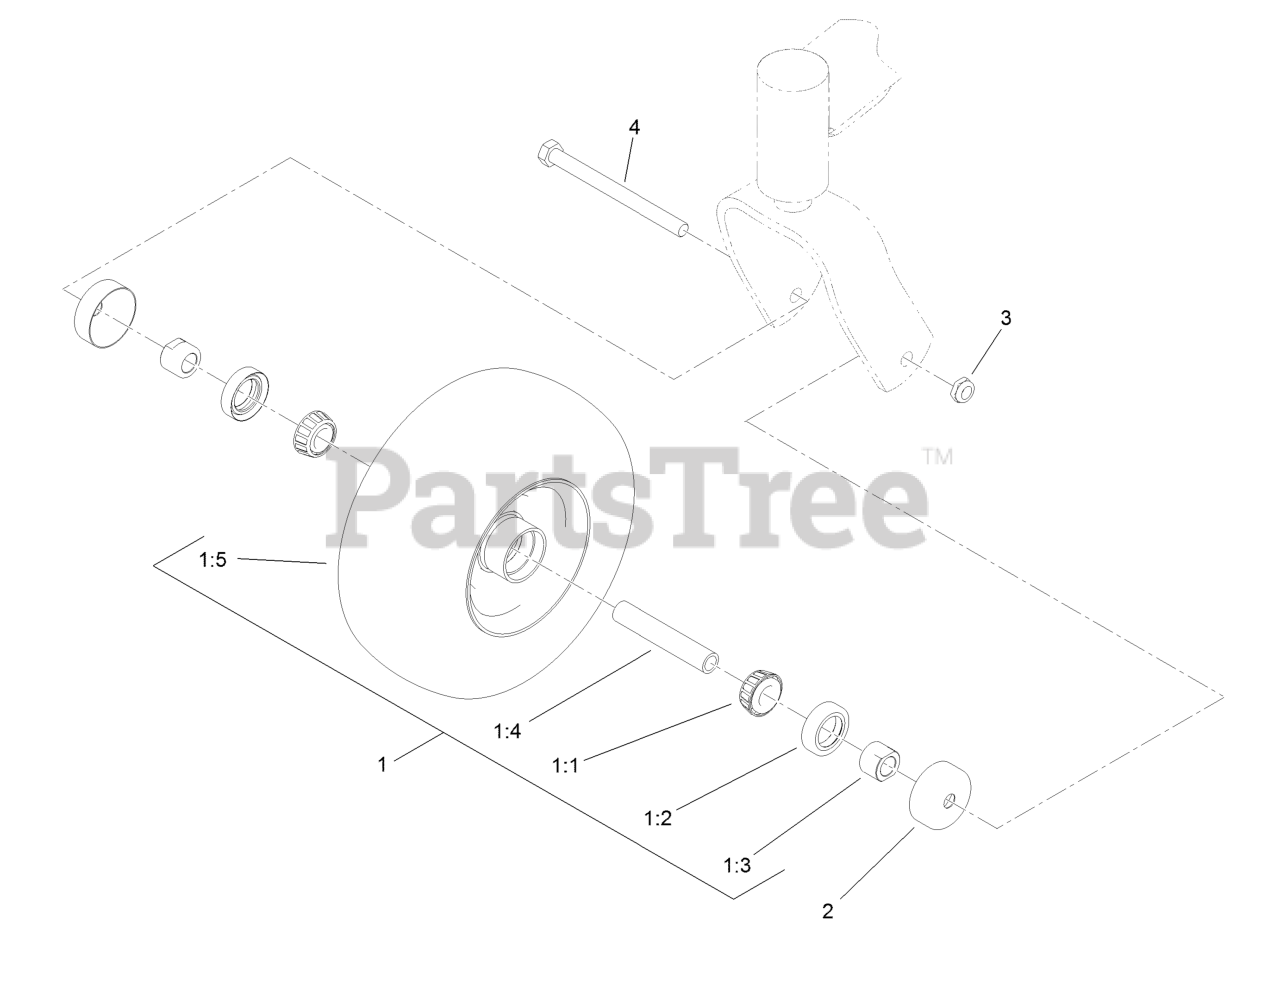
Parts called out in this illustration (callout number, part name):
1	Wheel And Bearing ASM
1:1	Bearing-Cone Tapered Roller
1:2	Seal-Double Lip
1:3	Spacer-Nut
1:4	Caster Axle ASM
1:5	Wheel And Tire ASM
2	Guard-Seal
3	Nut-Nyloc 1/2-13 Thin
4	Screw-HH 1/2-13 X 6
